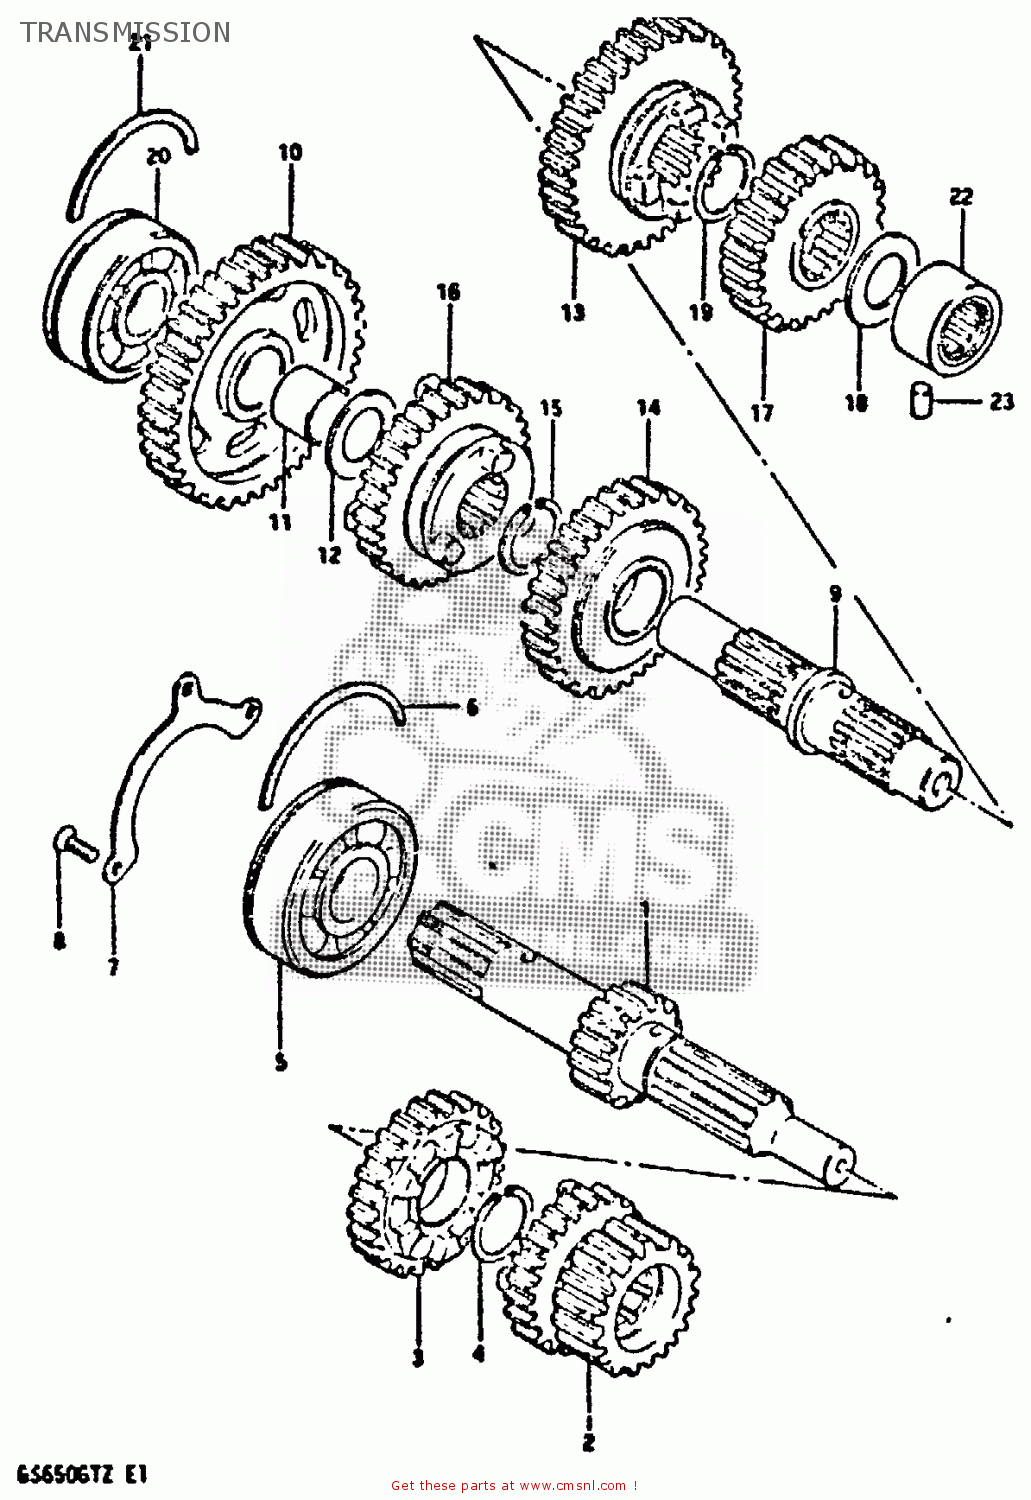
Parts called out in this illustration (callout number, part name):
1	SHAFT,COUNTER
2	GEAR,SECOND DRIVE
3	GEAR,FOURTH DRIVE
4	CIRCLIP
5	BEARING(25X62X17)
6	C-RING
7	RETAINER,CNTR SHAFT BEARING
8	SCREW
9	SHAFT,DRIVE
10	GEAR,FIRST DRIVEN
11	BUSHING
12	WASHER
13	GEAR,SECOND DRIVEN
14	GEAR,THIRD DRIVEN
15	CIRCLIP
16	GEAR,FOURTH DRIVEN
17	GEAR,REDUCTION(NT:24)
18	THRUST WASHER,REDUCTION
19	CIRCLIP
20	BALL BEARING 20X47X14
21	C RING
22	BEARING(20X34X16)
23	PIN
